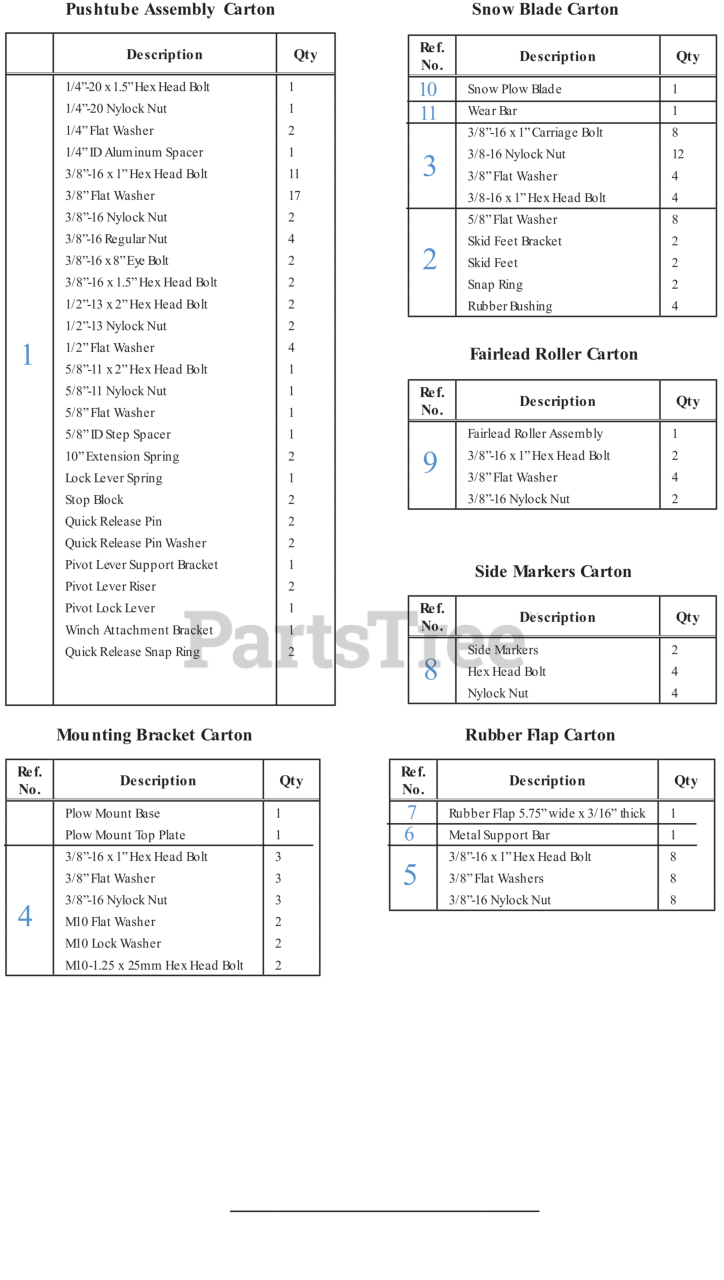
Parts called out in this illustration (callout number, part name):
1	PUSHTUBE REPLACEMENT HARDWAR KIT
2	SKID FEET SET (2 PIECES)
3	72" WEAR BAR HARDWARE
4	72" PLOW MOUNT HARDWARE KIT
5	72" RUBBER FLAP HARDWARE KIT
6	72" HOLD DOWN BAR
7	72" RUBBER FLAP
8	FLAG MARKERS SET (2 PIECES)
9	PLOW ROLLER KIT W/ROPE
10	72" PLOW BLADE
11	72" STANDARD WEAR BAR
11	72" POLY WEAR BAR
